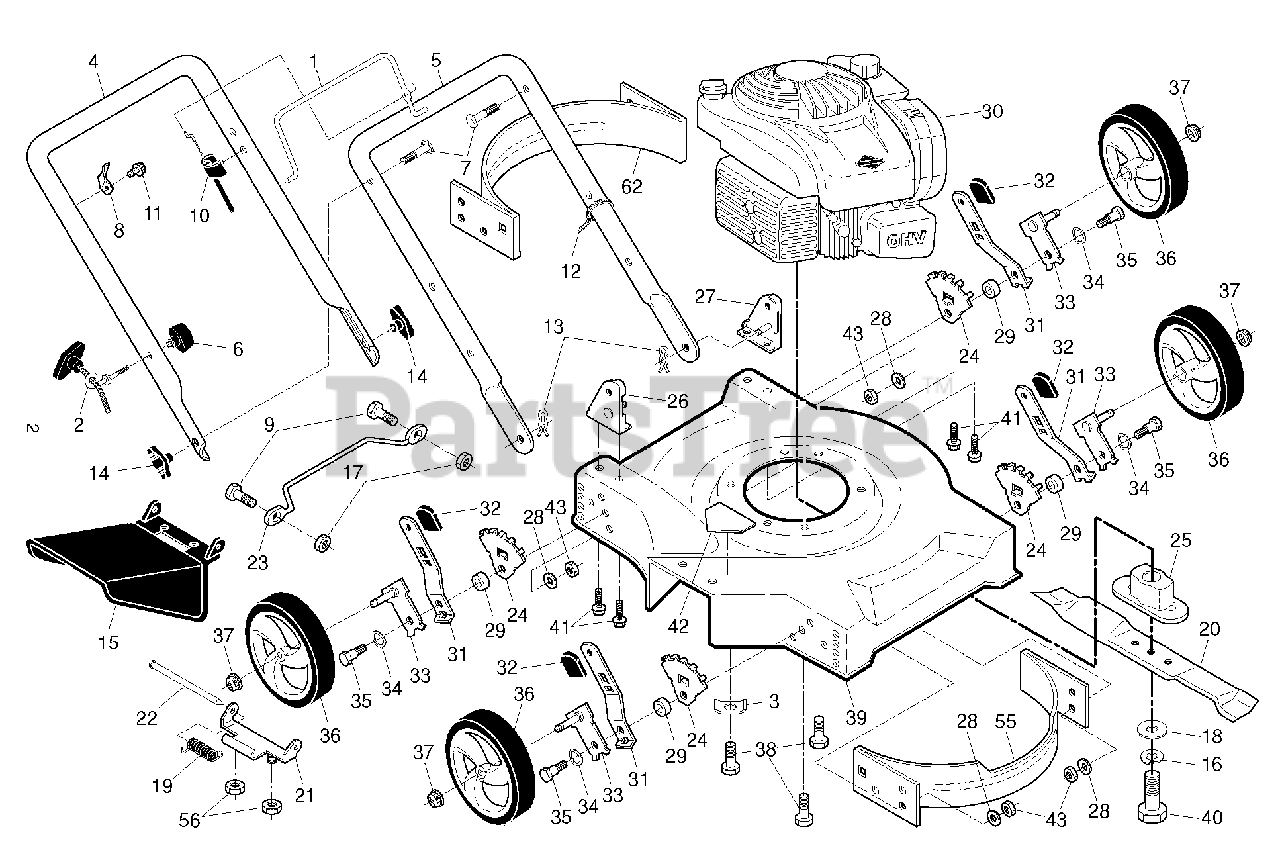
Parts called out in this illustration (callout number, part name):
1	BAIL.CONT.D.STRAIGHT.PUSH.BLK
2	Rope Guide, Blk Zinc Chrom
4	HANDLE.UPPER.FGD/PUSH.BLACK
6	T-Knob, New Rope Guide
7	BOLT, HANDLE 5/16-18X1.75
8	BRACKET.UPSTOP.RT
10	CABLE.MZR.RATO.22"LOW.
12	TIE GUIDE
13	HAIRPIN COTTER
14	KNOB, DEFLECTOR
16	LOCKWASHER
18	WASHER,HARDEN
20	BLADE.20.MULCH.(50DK,6020MD)
21	HINGE DEFLECTOR
22	HINGE ROD
24	WHEEL ADJ BRACKET FRONT
25	Blade Adapter, 7/8
26	HANDLE BRACKET ASM. RH
27	HANDLE BRACKET ASM. LH
28	WASHER
29	SPACER.HEIGHT.ADJUSTER
31	SELECTOR SPRING, FRONT
33	AXLE ARM ASSY.
34	WASHER FLAT
35	SHOULDER BOLT 5/16-18
37	NUT.HEX.FLANGE.3/8-16.LOCKNUT
38	BOLT 3/8-16X1-1/8
40	SCREW, HEX HD 3/8-24 X 1-3/8
41	SCREW 5/16-18
42	DECAL.INTERNATIONL.CUTFINGER
43	NUT.CENTERLOCK.5/16-
56	LOCKNUT
62	REAR BAFFLE
